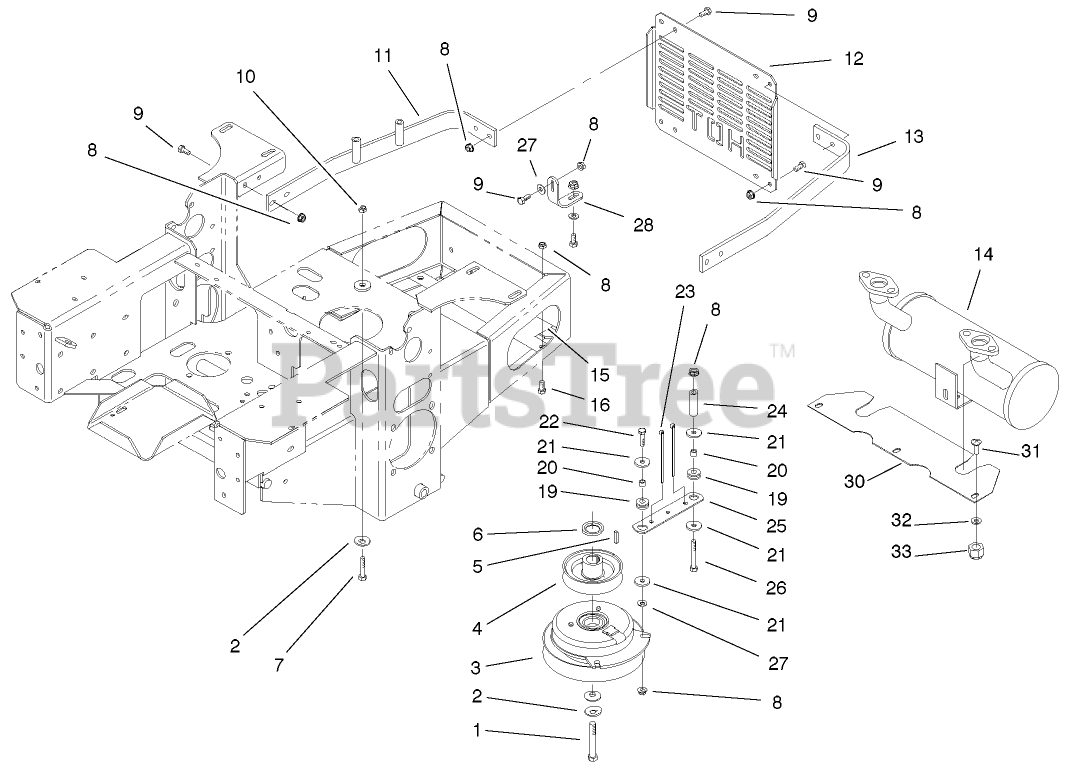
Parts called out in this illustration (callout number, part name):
1	SCREW-HH
2	WASHER-SPRING
3	Clutch,Mag Stop
4	PULLEY
6	SPACER-CRANKSHAFT
7	SCREW-HH
8	NUT-HF
9	SCREW-HH
10	NUT-LOCK, NI
11	STRAP-GUARD, ENGINE
12	SHIELD-ENGINE
13	STRAP-GUARD, ENGINE
14	Muffler
15	Deflector,Lower Frame
16	SCREW-HH
19	GROMMET
20	SPACER
21	WASHER
22	SCREW-HH
23	TIE-PLASTIC
24	BUSHING-MOUNT, SEAT
25	STRAP-CLUTCH, BRAKE
26	SCREW-HH
27	WASHER-FLAT
28	BRACKET-SUPPORT, MUFFLER
30	SHIELD-HEAT
31	BOLT-CARR
32	WASHER-PLAIN
33	NUT-LOCK, NI
